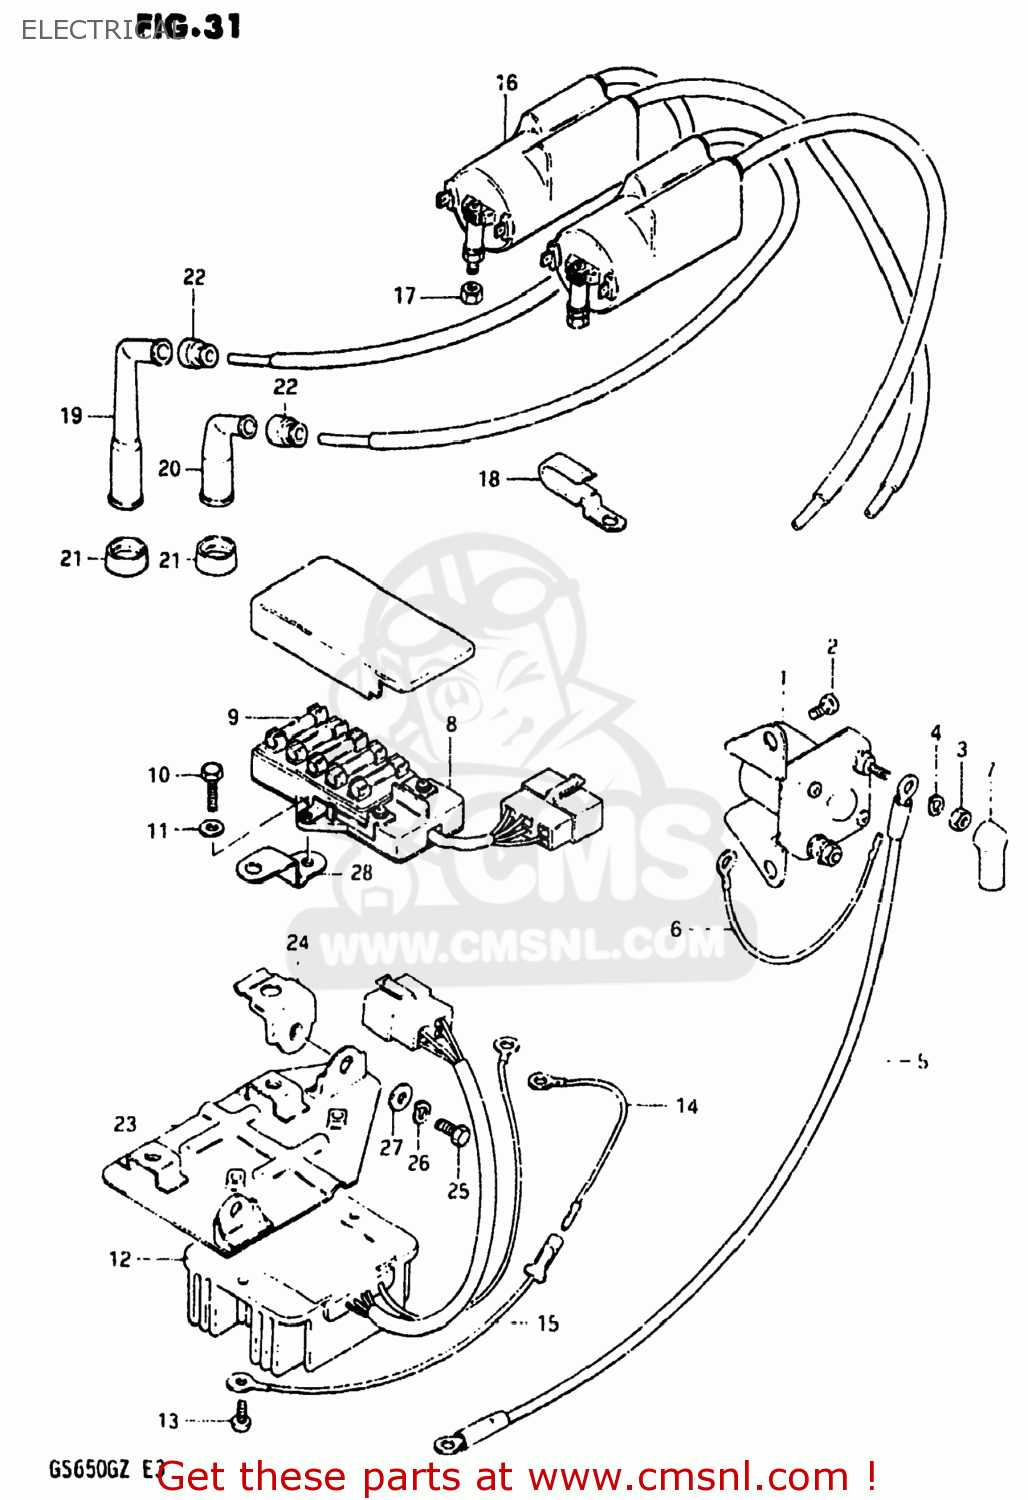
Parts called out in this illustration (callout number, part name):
1	RELAY ASSY,STARTING MOTOR
2	SCREW
3	NUT 6MM
4	LOCK WASHER
5	WIRE,STARTER MOTOR LEAD
6	LEAD WIRE
7	CAP,STARTER RELAY
8	BOX ASSEMBLY,FUSE
9	FUSE(15A)
10	BOLT, UPPER
11	WASHER
12	RECTIFIER ASSEMBLY
13	SCREW 6X12
14	LEAD WIRE
15	WIRE
16	COIL ASSEMBLY,IGNITION
17	NUT
18	CLAMP
19	CAP ASSY,SPARK PLUG
20	CAP,SPARK PLUG
21	SEAL,SPARK PLUG
22	SEAL,SPARK PLU
23	PLATE,ELECTRIC PARTS H
24	BRACKET, PARTS HOLDER
25	BOLT
26	LOCK WASHER
27	WASHER
28	BRACKET
